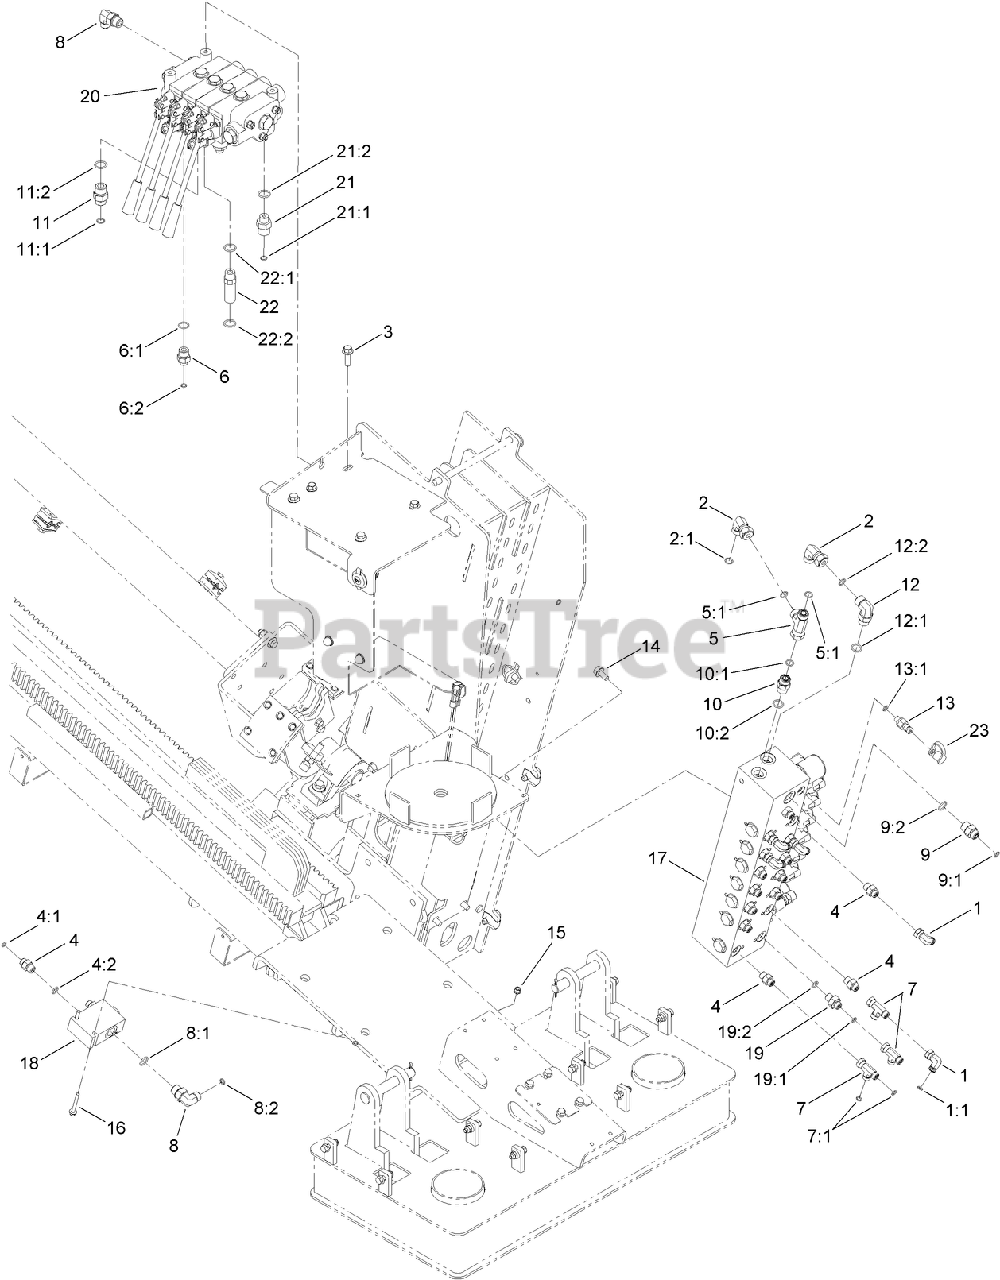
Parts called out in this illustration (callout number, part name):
1	FITTING-ADAPTOR
1:1	O-RING
2	FITTING-HYD
2:1	O-RING
3	SCREW-HHF
4	FITTING-STRAIGHT
4:1	O-RING
4:2	O-RING
5	FITTING-HYD, TEE
5:1	O-RING
6	FITTING-STR
6:1	O-RING
6:2	O-RING
7	FITTING-HYD
7:1	O-Ring
8	FITTING-HYD, 90 DEG
8:1	O-RING
8:2	O-RING
9	FITTING-STRAIGHT
9:1	O-RING
9:2	O-RING
10	FITTING-STRAIGHT
10:1	O-RING
10:2	O-RING
11	FITTING-STRAIGHT
11:1	O-RING
11:2	O-RING
12	FITTING-ELBOW-90 DEG
12:1	O-RING
12:2	O-RING
13	FITTING-QUICK
13:1	O-RING
14	SCREW-HHF
15	NUT-FLANGE, NI
16	SCREW-HHF
17	9 SECTION HYD VALVE ASM
18	HYD FLOW DIVIDER VALVE ASM
19	FITTING-STR,ORIF
19:1	O-RING
19:2	O-RING
20	4 SPOOL HYD VALVE ASM
21	FITTING-HYD, STRAIGHT
21:1	O-RING
21:2	O-RING
22	FITTING-STR
22:1	O-RING
22:2	O-RING
23	CAP-DUST
